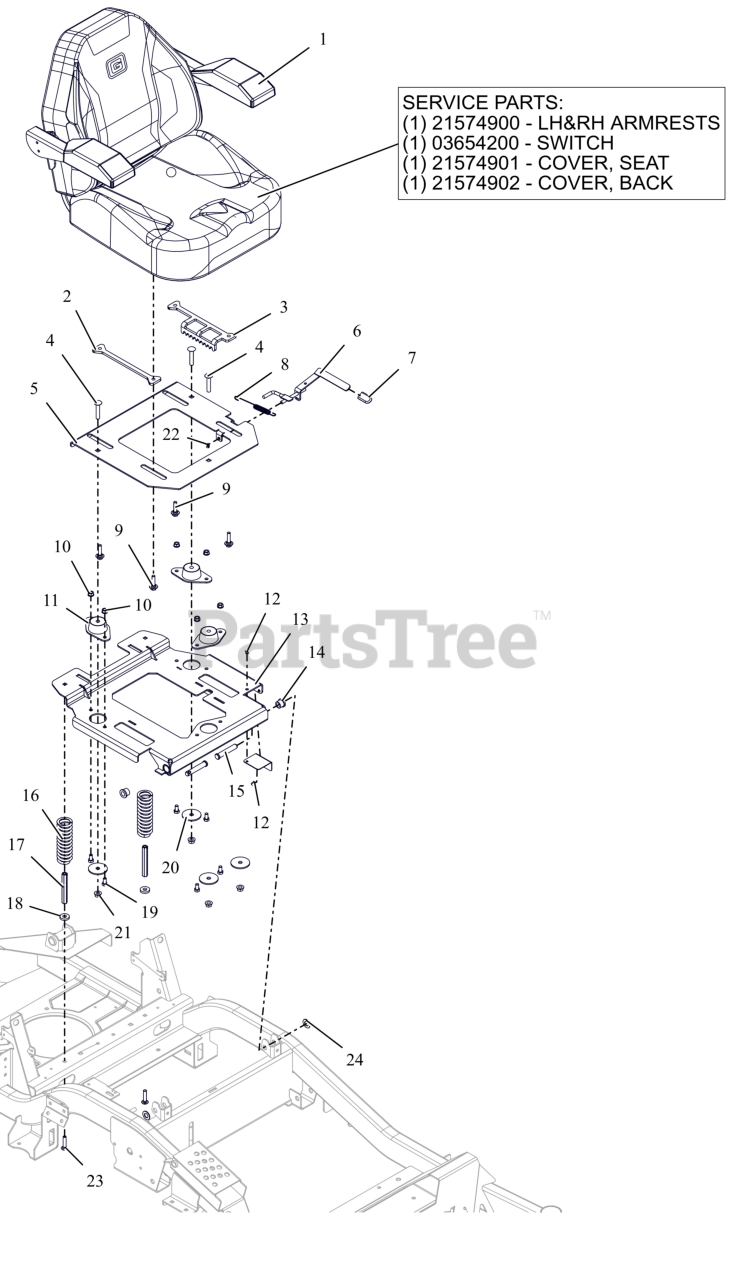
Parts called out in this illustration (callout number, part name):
1	SEAT, HD
1	LH&RH ARMRESTS
1	SWITCH- SEAT
1	COVER, SEAT - HD
1	SEAT COVER, BACK HD
2	PLATE, ADJ SEAT SLIDE (BLACK)
3	PLATE, SEAT ADJ (BLACK)
4	BLT,RHSSN.375-16X2.00 G5 ZCC
5	PLATE- SEAT MTG 3PT (ISO KIT)
6	WLDMT, SEAT SLIDE LEVER
7	GRIP, SEAT LEVER, GREY
8	SG-TENS .06X.482X5.35
9	BLT, SHLDR .31-18 X .175
10	NUT,LK-CTR-FLG .31-18 GF ZCC
11	MOUNT- FAIL-SAFE COMPRESSION
12	RIVET, .1875 AL/AL .126-.250
13	WLDMT- ISO MTG PLATE 3PT
14	BSHG, FLG .516X.750X.625X.937
15	PIN, SLIC-.500X42.70X2.31 -ZC
16	SPRING, COMPRESSION SEAT 224LB
17	NUT, COUPLING 5/16X18 X 3.75
18	WSHR, FLT .406X1.00X.188 ZCC
19	BLT, HEX .31-18X.625 G5 ZCC
20	WSHR-FL-STL 0.406X2X0.125 ZCC
21	NUT-LK-CTR-FLG .375-16 GF ZCC
22	NUT-PUSH .312
23	BLT,RHSN .31-18X1.50 G5 ZCC
24	WSHR, FLT .531X1.00X.063 ZCC
